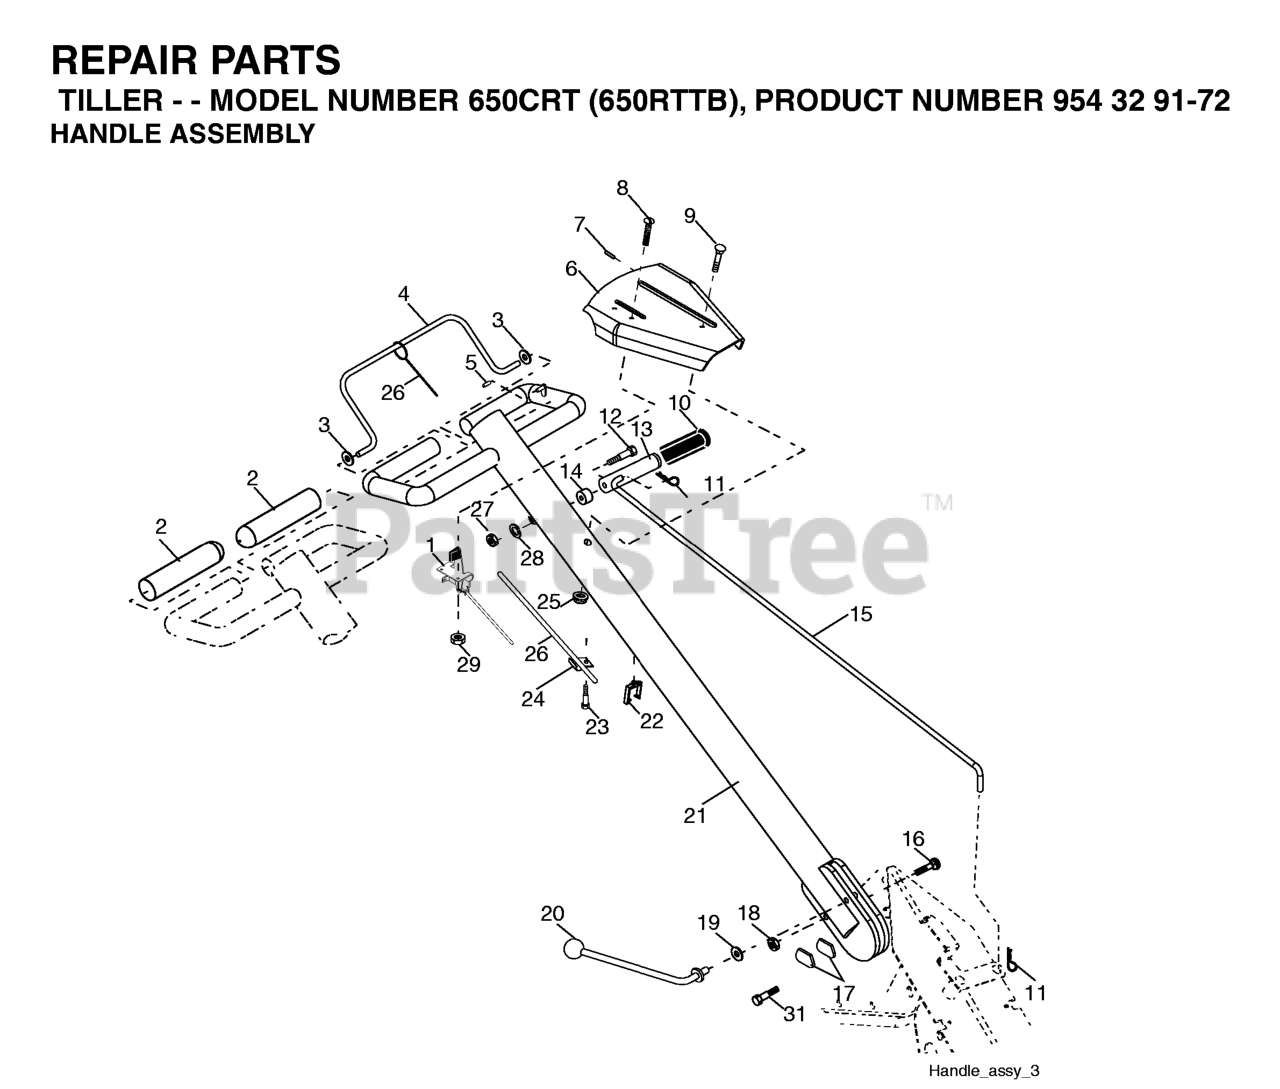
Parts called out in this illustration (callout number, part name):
1	THROTTLE.CONTROL.CRT.TILLER
2	GRIP.HANDLE.TILLER
3	GROMMET HANDLE
4	BAR ASSEMBLY, CONTROL
6	PANEL, CONTROL
7	BUSHING SPLIT
8	SCREW.PNHD.10-24
9	BOLT.5/16-18X2.5
10	GRIP, HANDLE
11	RETAINER M
12	SHOULDER BOLT ST
13	HANDLE, SHIFT
14	GROMMET.RUBBER.CRT.TILLER
15	ROD, SHIFT
16	BOLT D
17	LOCK.HANDLE.CRT
19	WASHER CRT
20	LEVER.LOCK.CRT
21	HANDLE
22	CLIP CABLE
23	TAPPING SCREW
24	CONDUIT.CLIP.PLATED
25	NUT.CENTERLOCK.5/16-
26	CABLE, CLUTCH
27	NUT T
29	NUT **
31	BOLT.PIVOT
